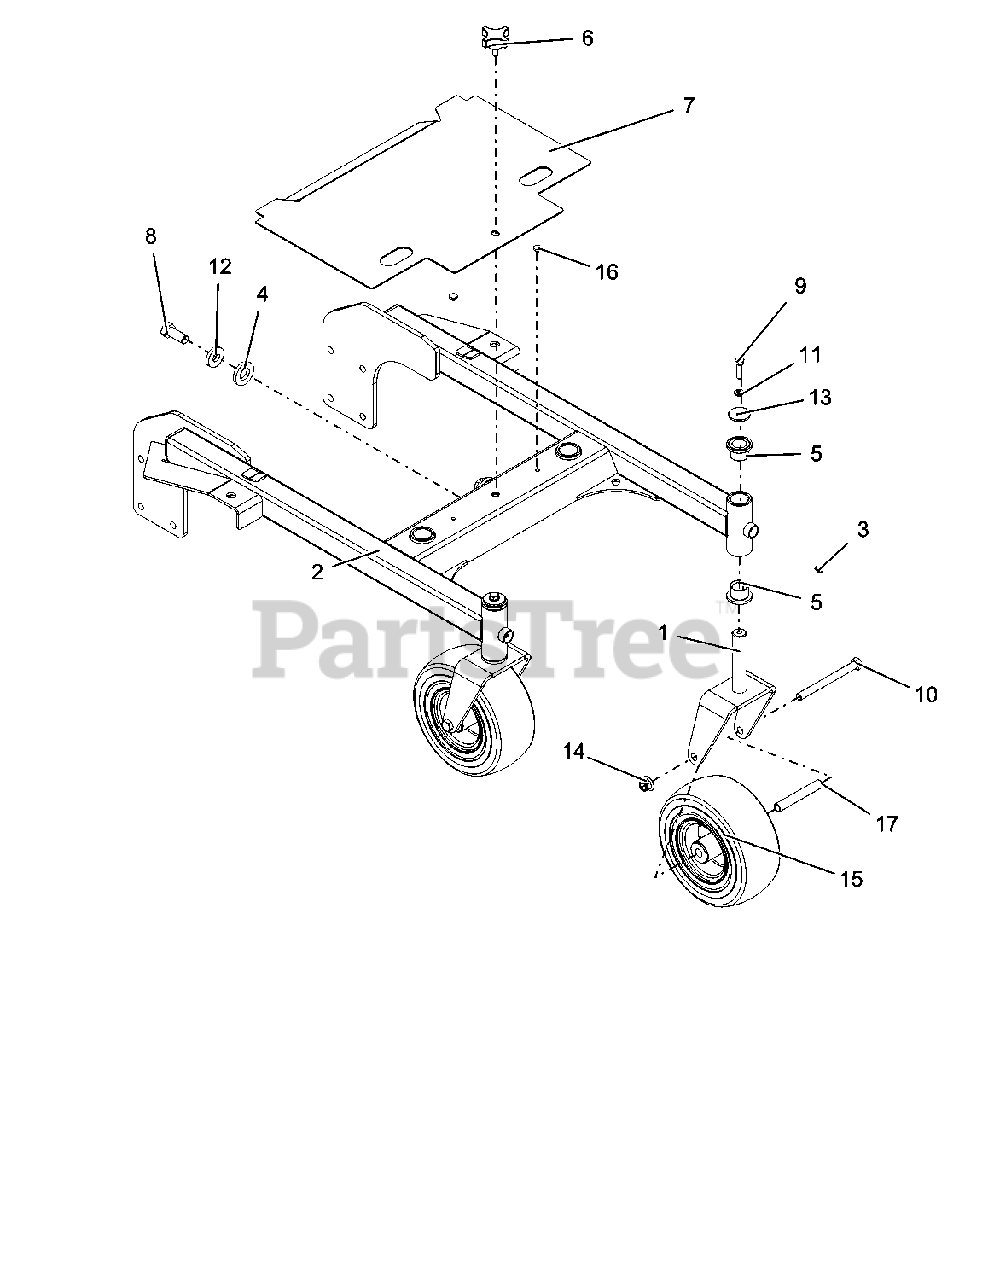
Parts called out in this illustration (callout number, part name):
1	WLDMT, FRONT WHEEL FLOAT WALK
2	WLDMT, FRAME CARRIER 36 HYD WLK (RED)
3	FTG, 1/4-28 STRGT GREASE ZERK
4	WSHR-FL-STL .905X1.750X.25 YWZC
5	BRG, FLANGE 1.00 X 1.25 X 1.00
6	KNOB, 3/8-16 x .75
7	SHIELD, BELT 36" HYD WLK-RED
8	BLT-HEX .62-11X1.50 GR8 YWZC
9	BLT-HEX .38-16X1.25 GR5 YWZC
10	BLT-HEX .50-13X5.50 GR5YWZC
11	WSHR-LK .38X.094 REG YWZC
12	WSHR-FL-STL .630X1.50X.25 YWZC
13	WSHR-FL-STL .380X1.50X.125 YWZC
14	NUT-LK-NYL-FLG .50-13 YWZC
15	9X3.5-4 CAREFREE BLT TOGETHER
16	BUMPER GROMMET .125 X .25 REV
17	TUBE, CASTER AXLE
